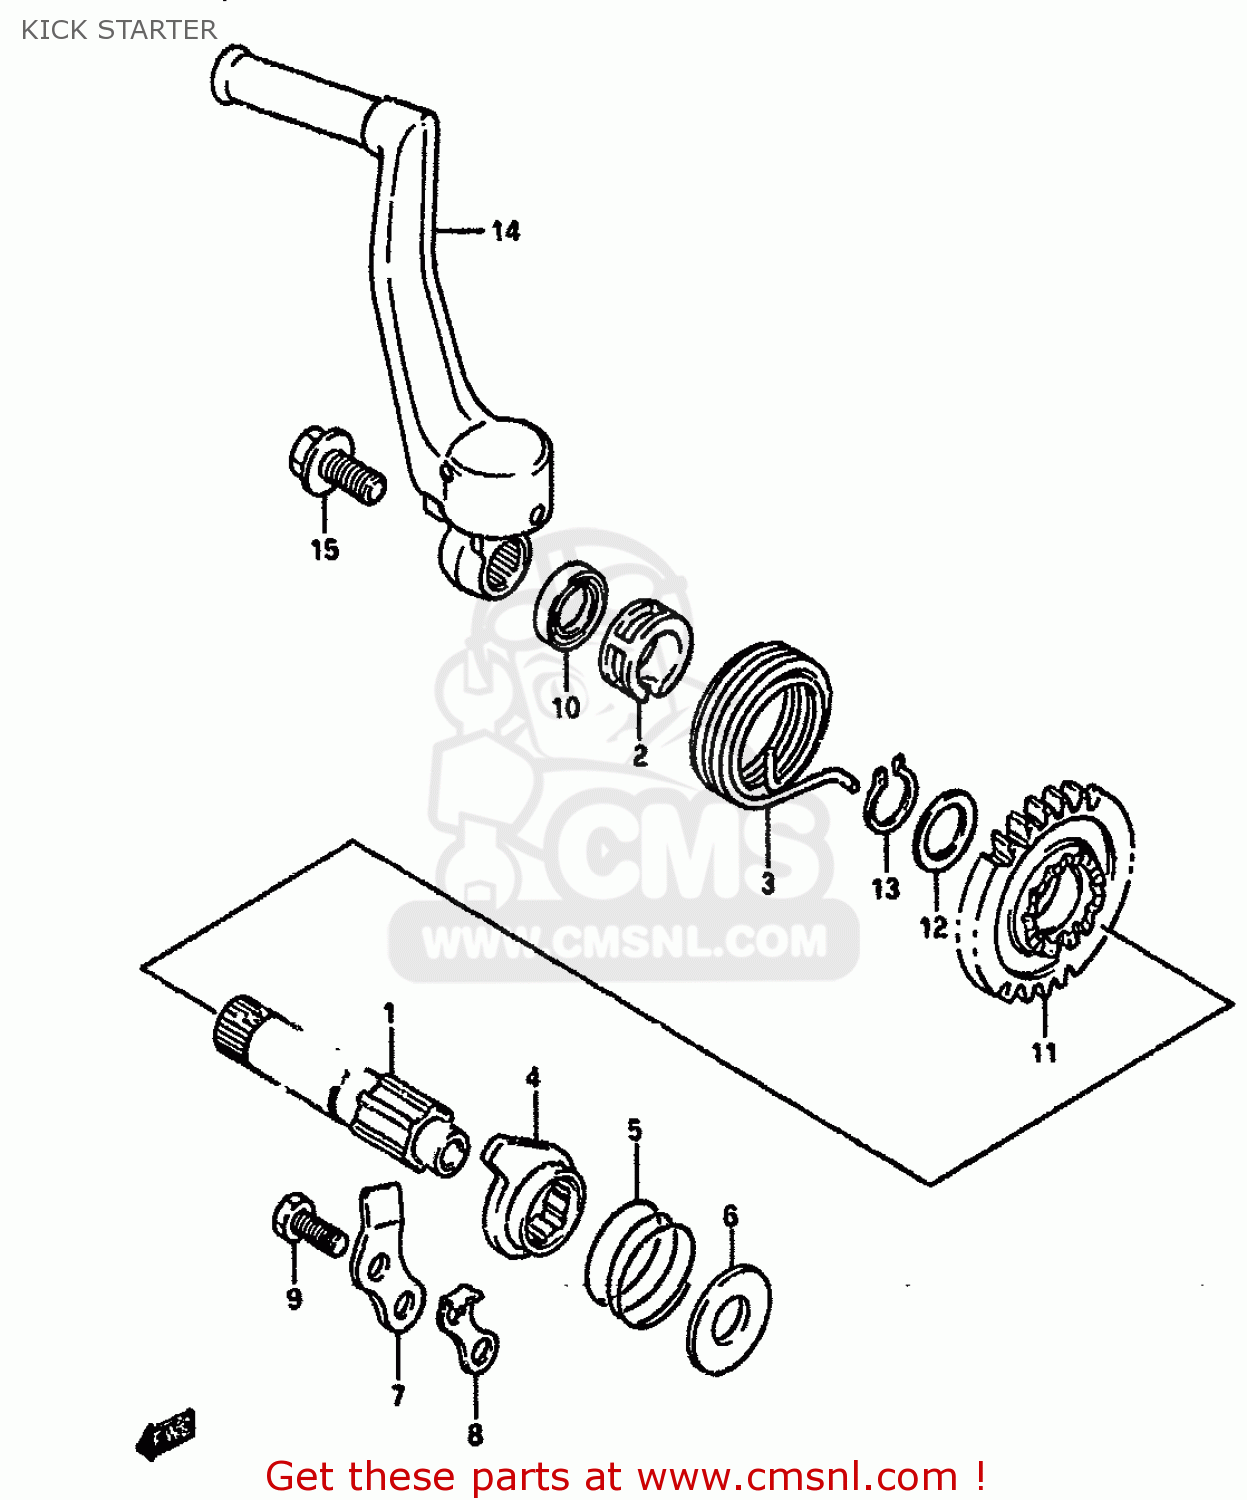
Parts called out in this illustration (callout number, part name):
1	SHAFT,KICK STARTER
2	GUIDE,KICK STARTER SFT SPRING
3	SPRING
4	STARTER,KICK
5	SPRING
6	WASHER
7	GUIDE,KICK STARTER
8	STOPPER,KICK STARTER
9	BOLT
10	SEAL,OIL(16X24X5)
11	GEAR,KICK STARTER DRIVE
12	WASHER
13	CIRCLIP,16MM
14	LEVER ASSEMBLY,KICK STARTER
15	BOLT(8X14)
